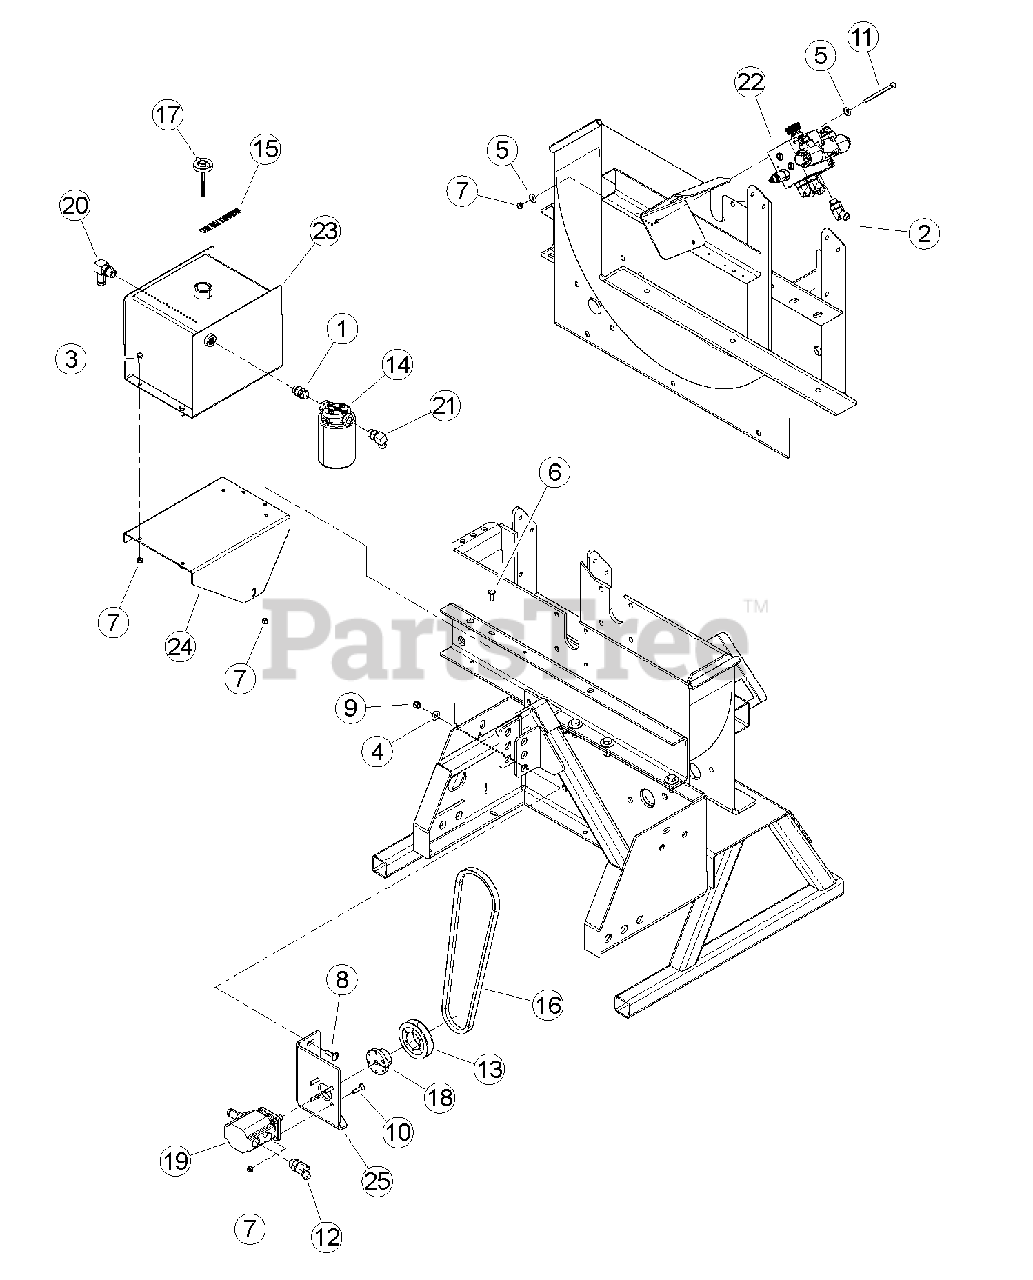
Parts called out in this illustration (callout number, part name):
1	ADAPTER, -8 MORING / -8 MORING ADJ
2	ADAPTER, -8 MORB / - 8MJIC 45 DEG.
3	BOLT, 5/16 X 3/4 HEX GR5 ZP
4	WASHER, 3/8 FLAT ZP
5	WASHER, 5/16 FLAT ZP
6	BOLT, 5/16 X 1 CRG GR5 ZP
7	NUT, 5/16 NE NYLOCK ZP
8	BOLT, 3/8 X 1-1/4 CRG GR5 NC ZP
9	NUT, 3/8 NE NYLOCK ZP
10	BOLT, 5/16 X 1-1/4 CRG GR5 ZP
11	BOLT, 5/16 X 4 HEX GR5 ZP
12	ADAPTER, -10 MORING / -8 MJIC 45 DEG.
13	SHEAVE, 1B3.6 SH
14	ASSEMBLY, HYDRAUILC FILTER
15	DECAL, HYDRAULIC FLUID
16	BELT, BX44
17	CAP, W/DIPSTICK
18	BUSHING, SH 1/2
19	PUMP, 2 STAGE CW HI/LO 0.605 DISP.
20	ADAPTER, -10 MORING /.75 90 DEG. HOSE
21	ADAPTER, -8 MORING / -8 MJIC 90 DEG.
22	ASSEMBLY, HYDRAULIC FEED FLOW VALVE
23	WELDMENT, TANK HYDRAULIC 3.25 GAL
24	SHEET, MOUNT HYDRAULIC TANK
25	BRACKET, MOUNT HYDRAULIC PUMP
